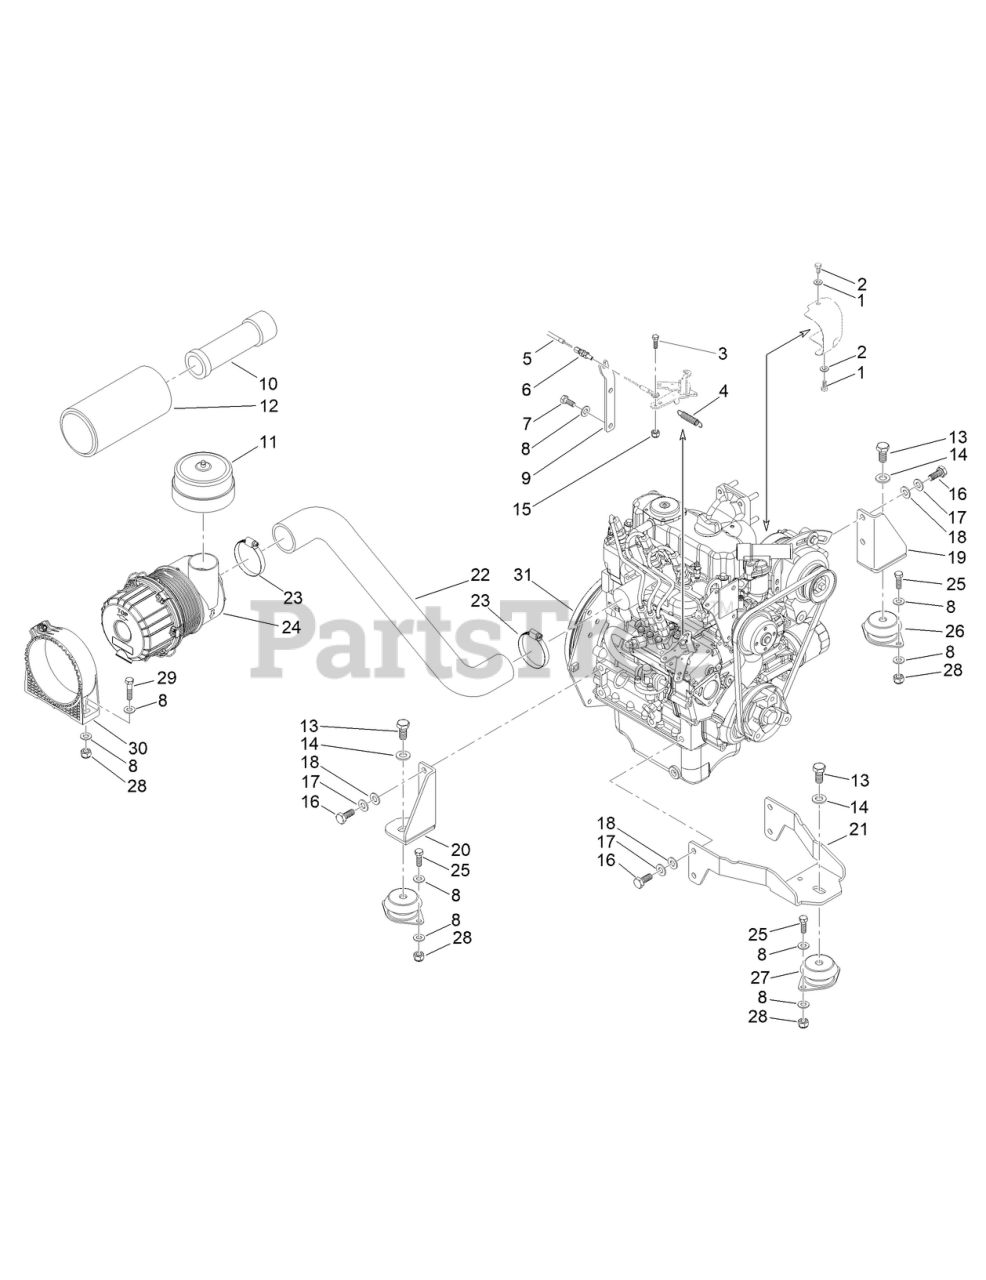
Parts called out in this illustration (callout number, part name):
1	SCREW-HH, CAP
2	WASHER
4	SPRING
5	CABLE, THROTTLE
6	SCREW HH
8	WASHER
9	BRACKET, THROTTLE CABLE
10	ELEMENT-AIR FILTER, INNER
11	PREFILTER-AIR
12	CARTRIDGE-FILTER
14	WASHER
17	WASHER
18	WASHER
19	SUPPORT-FRONT, ENGINE RH
20	SUPPORT-FRONT, ENGINE LH
21	ENGINE SUPPORT, REAR
22	HOSE, ENGINE INTAKE
24	FILTER-AIR
26	SHOCK ABSORBER
27	SHOCK ABSORBER
31	ENGINE (KUBOTA D722 E4B)
